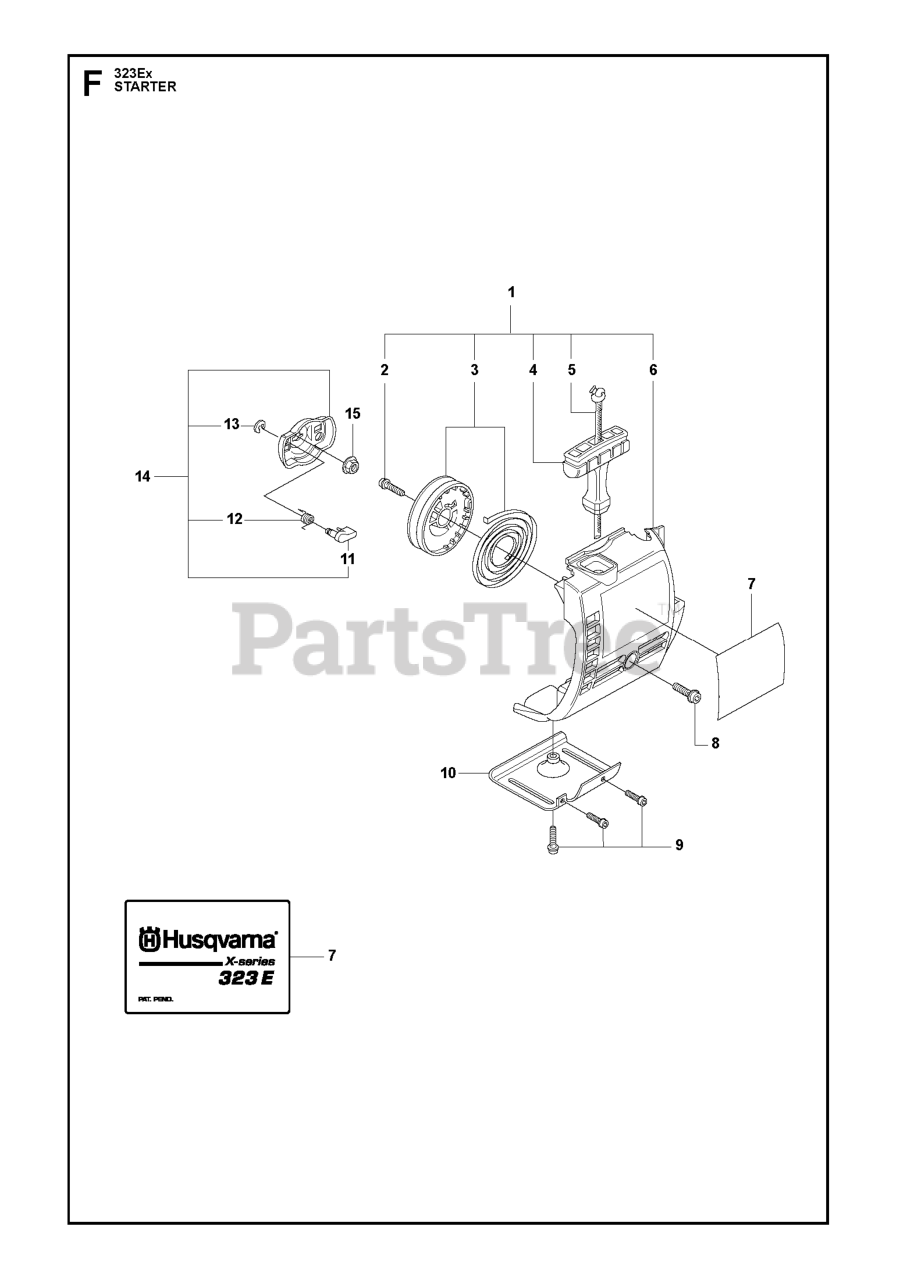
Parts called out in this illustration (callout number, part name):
1	STARTER ASSY
3	STARTER PULLEY ASSY.
4	STARTER HANDLE
5	STARTER ROPE
6	STARTER HOUSING
7	LABEL 323 EX
8	SCREW
9	SCREW
11	STARTER PAWL
14	PAWL ASSY COMPLETE
15	FLANGE NUT
